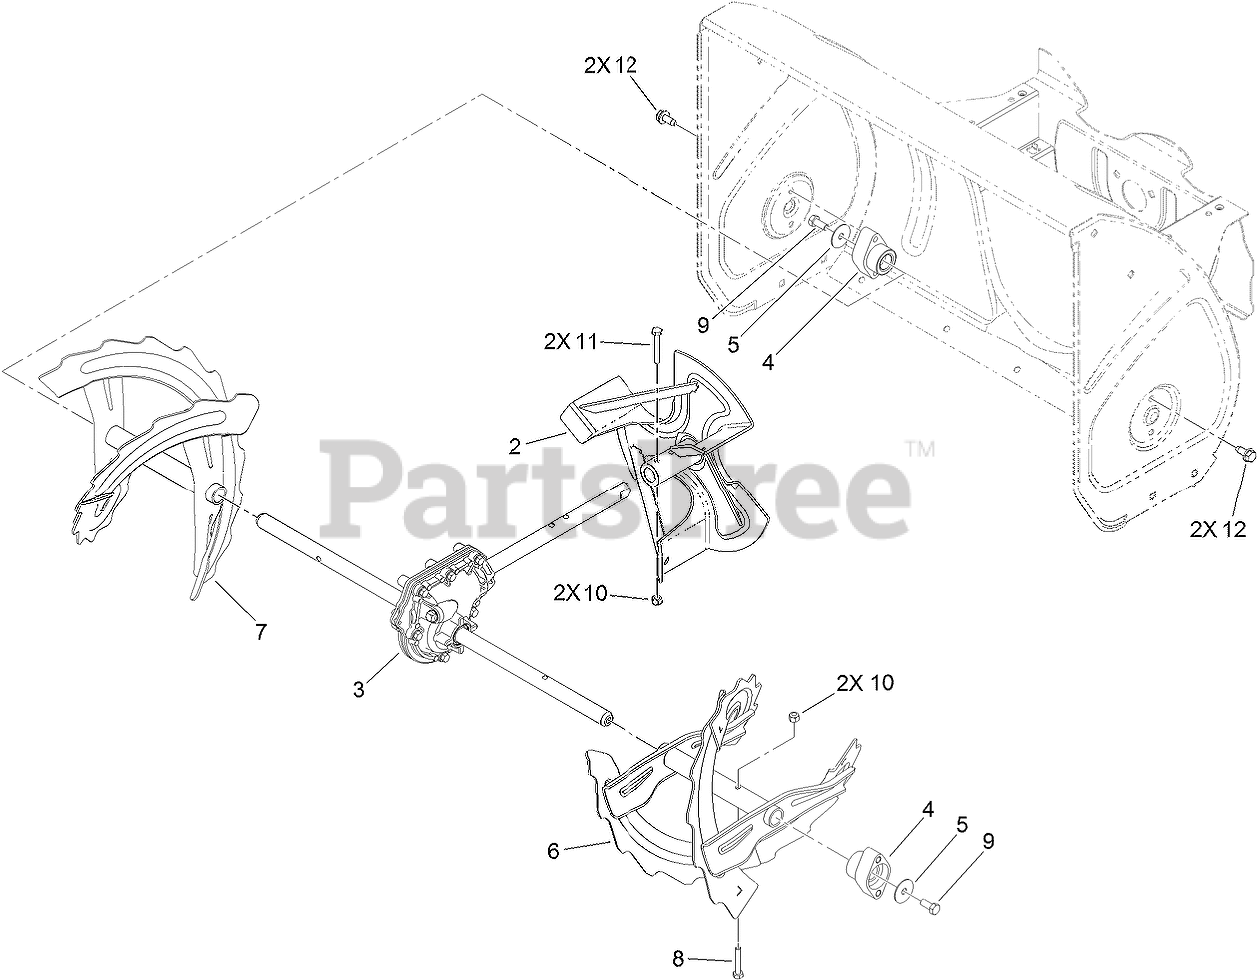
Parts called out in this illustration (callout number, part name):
2	IMPELLER ASM
3	GEARCASE ASM
4	BEARING-AUGER
5	WASHER-THRUST
6	LH AUGER ASM
7	RH AUGER ASM
8	CAPSCREW
9	SCREW-HH
10	NUT-LOCK, NI
11	SCREW-HH
12	SCREW-HWHTF
